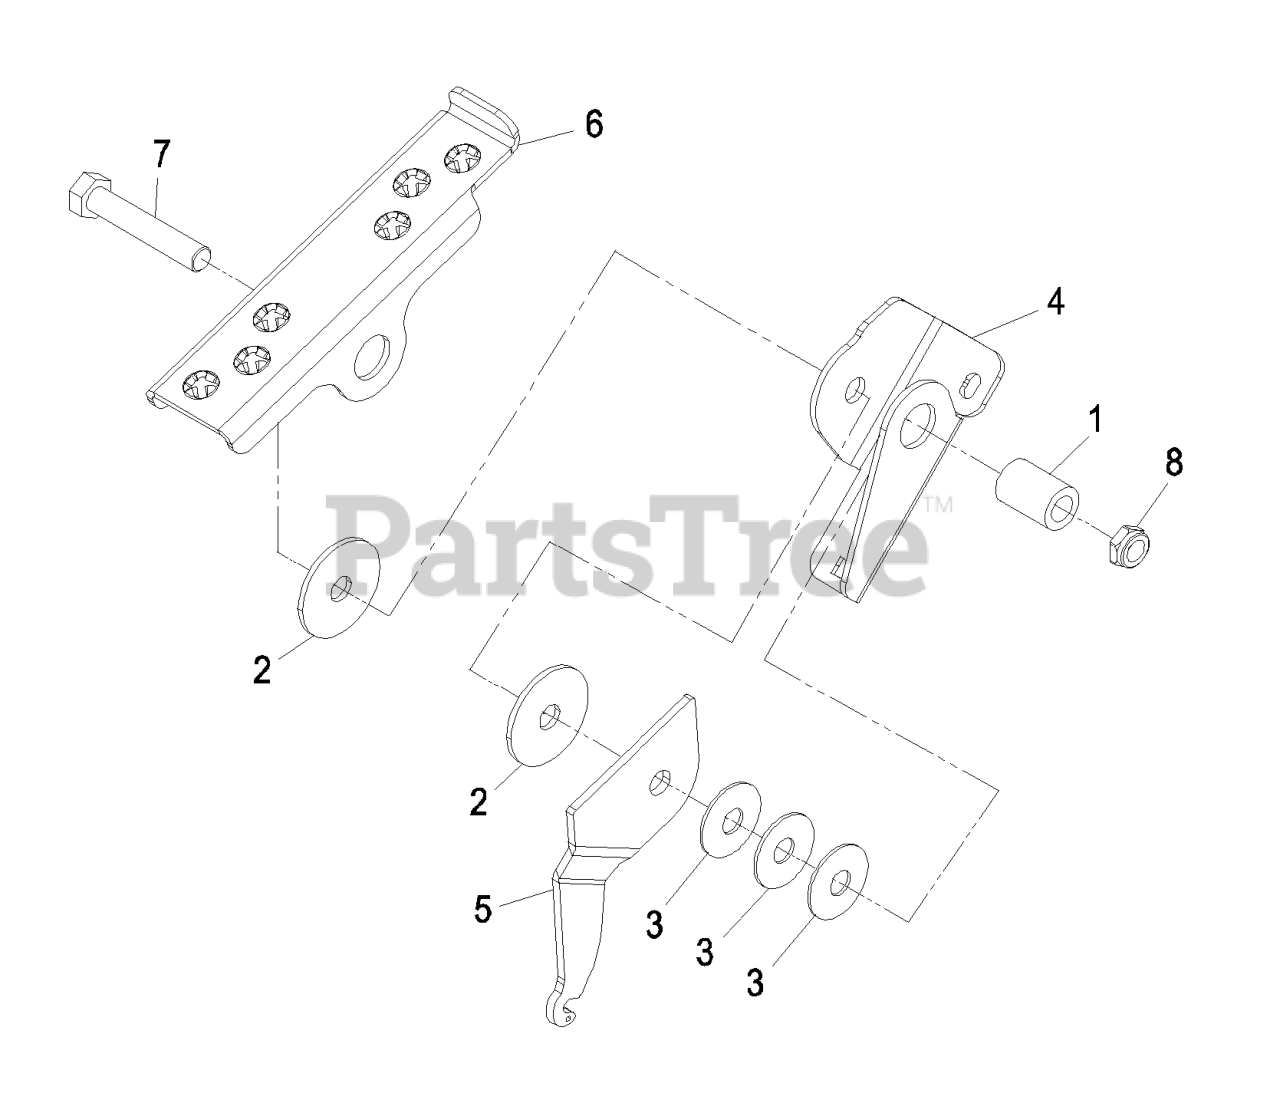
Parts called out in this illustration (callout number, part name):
1	SPACER-ROLLER
2	DISC-FRICTION
3	WASHER-DISC, SPRING
4	BRACKET,PEDAL PIVOT
5	BRACKET,PEDAL LINK
6	CHANNEL,PEDAL LINK
7	SCREW-HH
8	NUT-HEX
